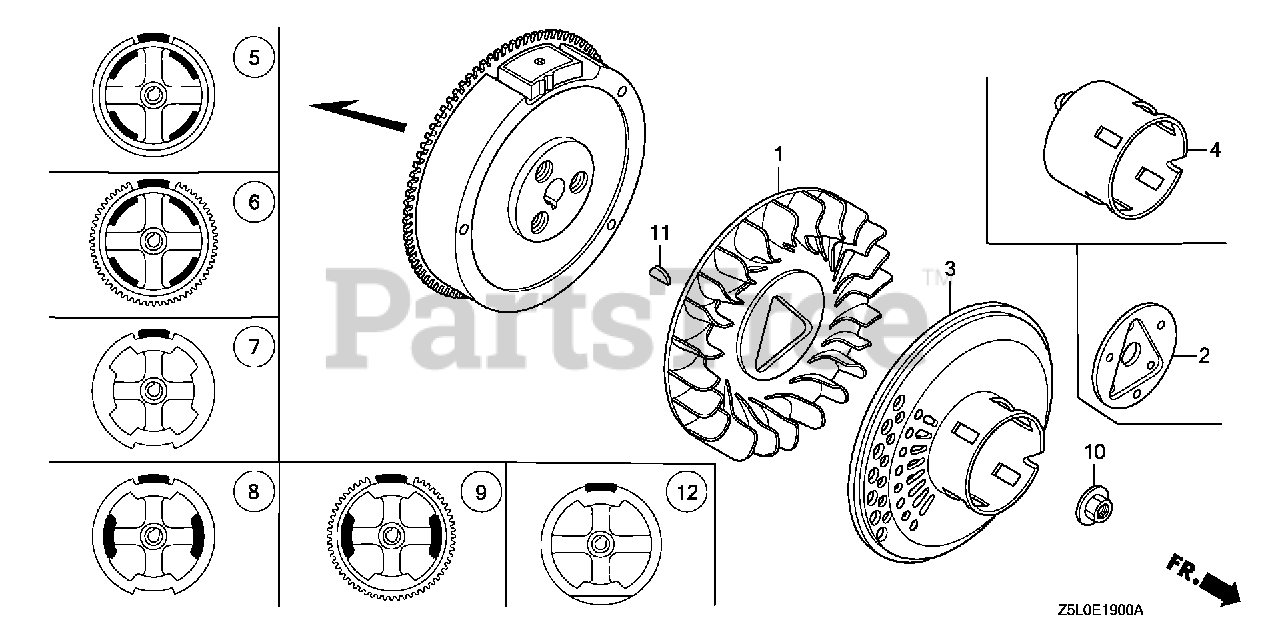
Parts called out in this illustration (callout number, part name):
1	FAN, COOLING
4	PULLEY, STARTER
9	FLYWHEEL (SEL-LAMP)
10	NUT, SPECIAL (16MM) (1)
10	NUT, SPECIAL (16MM)
11	KEY, SPECIAL WOODRUFF (25X18)
